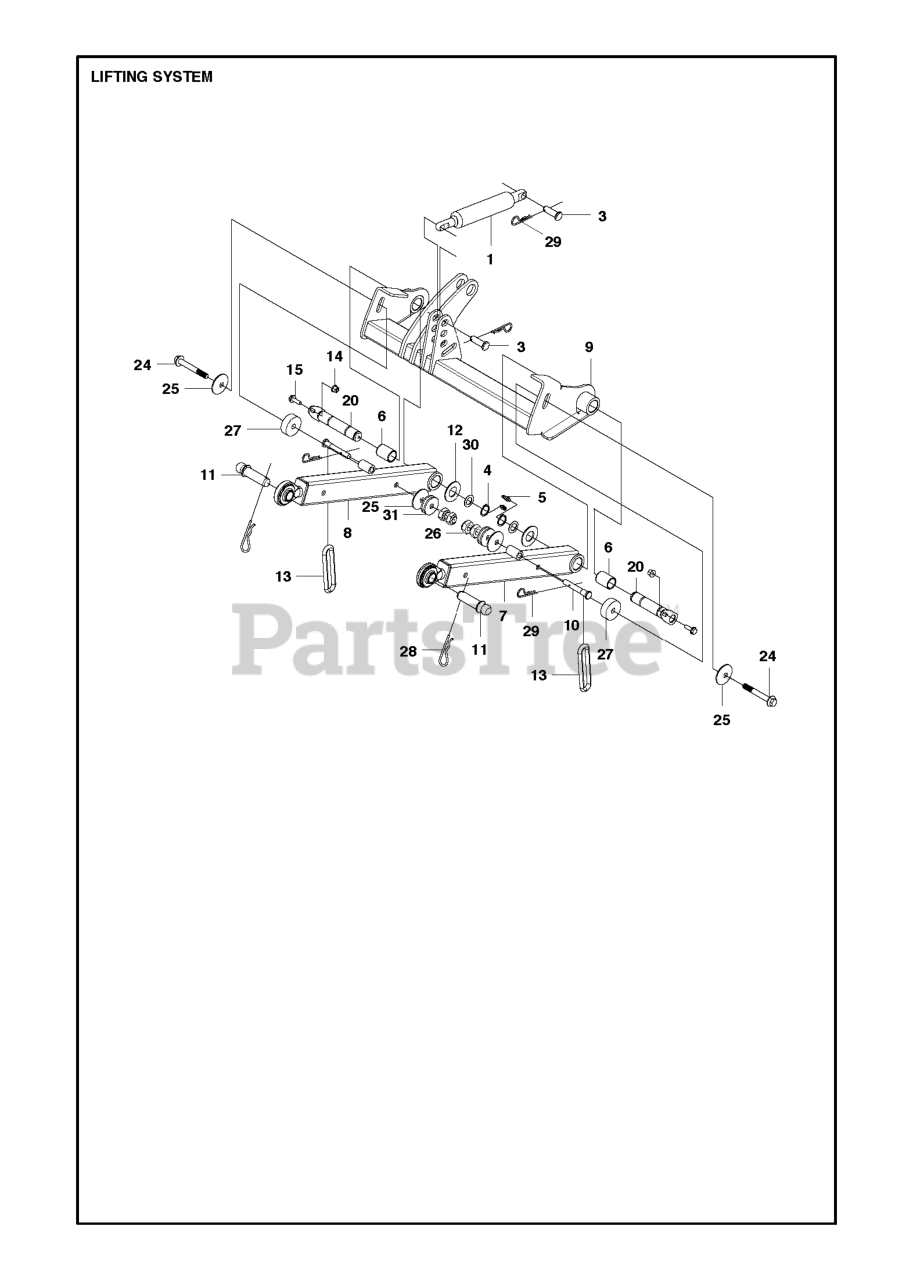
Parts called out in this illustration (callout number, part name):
3	CLEVIS PIN
11	BOLT LIFTING ARM
13	LINK
14	NUT FLANGE
15	BOLT
26	NUT HEXAGON THIN ISO 4035 M12
